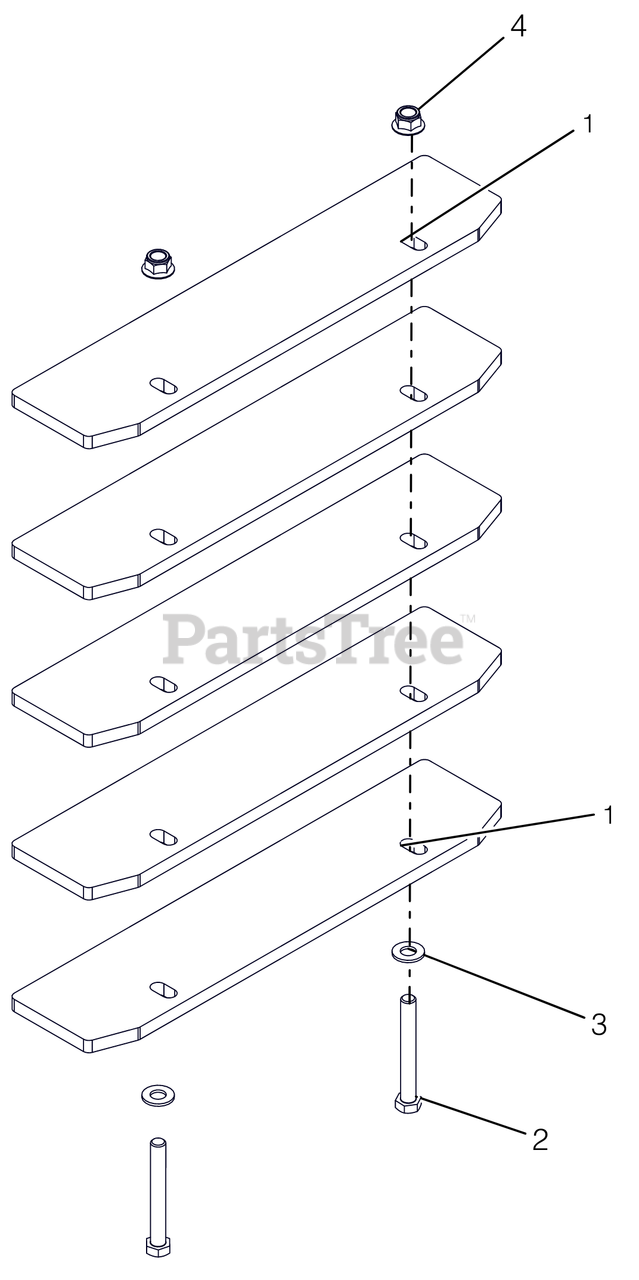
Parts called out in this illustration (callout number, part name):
1	PLATE, COUNTER WEIGHT
2	@BLT-HEX .50-13X4.00 GR5 YWZC
3	@WSHR-FL-STL.531X1.06X.095YWZC
4	@NUT-LK-NYL-FLG .50-13 YWZC
